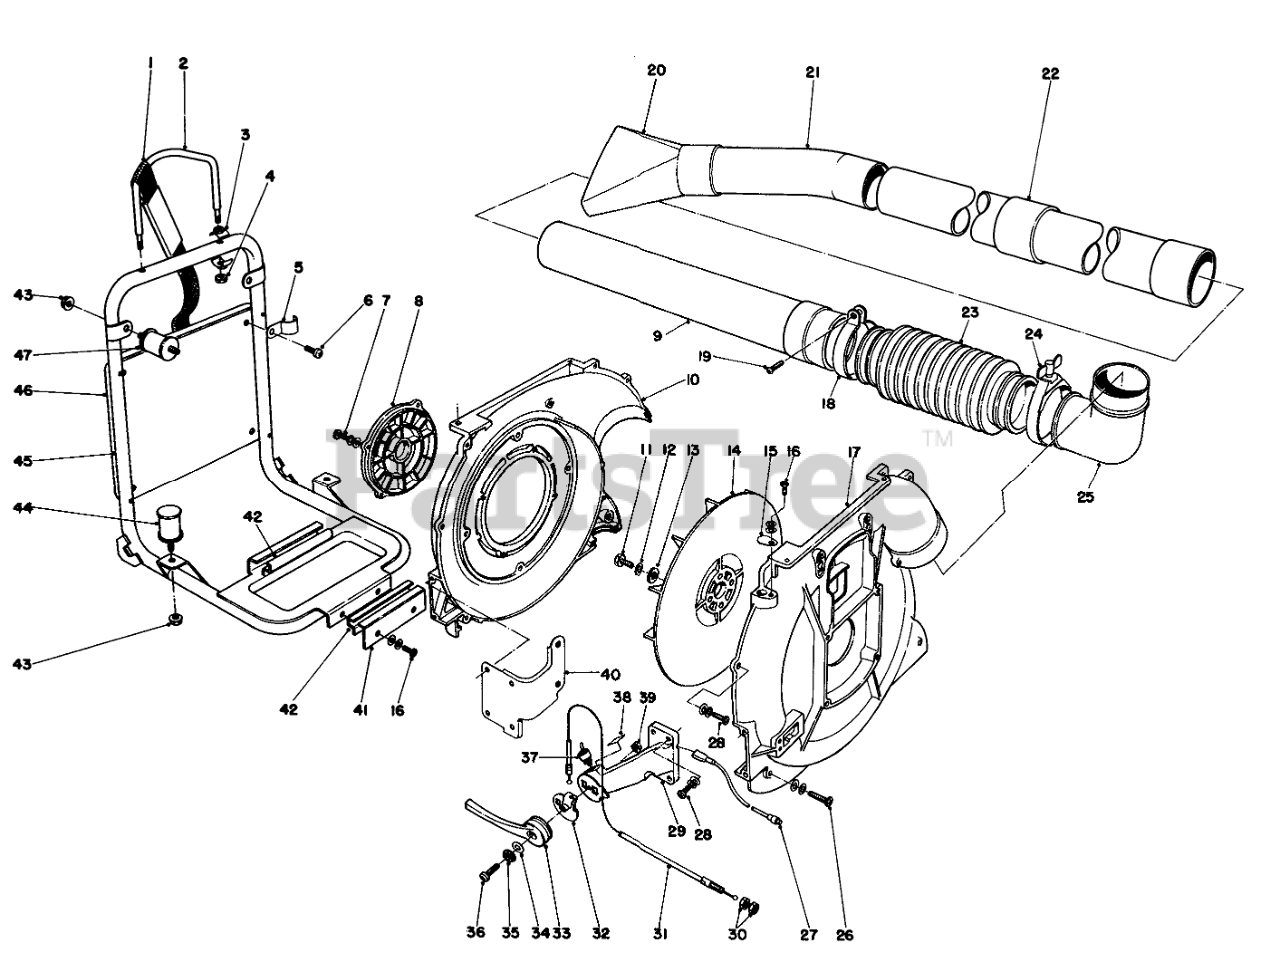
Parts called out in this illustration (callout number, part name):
1	Shoulder Strap
3	Adapter
4	Locknut
5	Bracket Cushion
6	SCREW-SHWH
7	Screw
8	Grid, Fan Case
9	STRAIGHT PIPE/SWIVEL
10	Fan Case, Operator Side
12	Washer
13	WASHER
16	SCREW
17	Fan Case, Starter Side
18	Clamp
19	Screw
20	FAN HD NOZZLE
21	CURVED PIPE
22	Straight Pipe
23	FLEXIBLE PIPE
24	CLAMP
25	Elbow
27	Lead Switch
28	Screw
29	THROTTLE LEVER BRKT
31	THROTTLE CABLE
33	THROTTLE LEVER
34	Washer
35	Washer
36	Screw
37	SWITCH
38	STOP SWITCH DECAL
40	Bracket
41	Bracket-Fuel Tank
42	Cushion-Fuel Tank
44	Cushion
45	Frame, Back Pack
46	Back Pack Pad
47	Cushion
